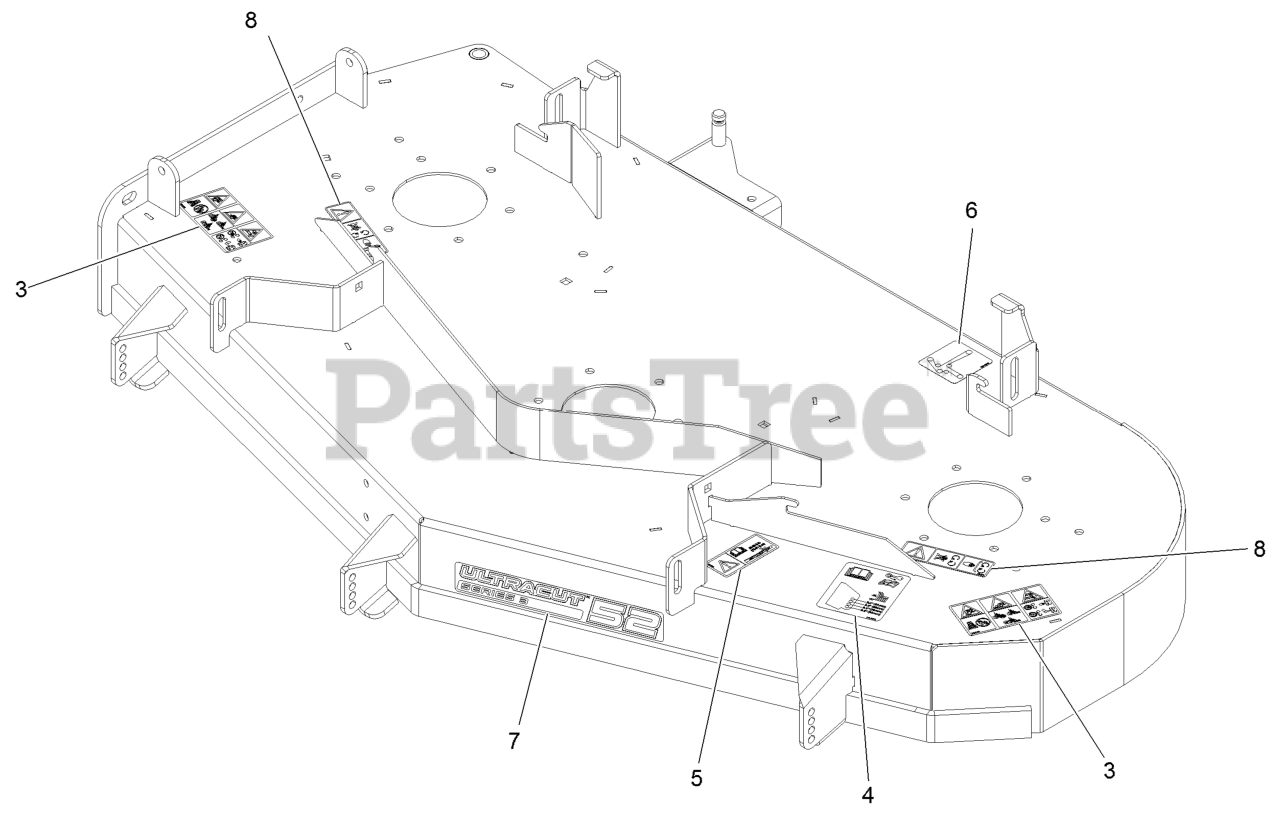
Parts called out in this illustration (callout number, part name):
3	DECAL-DANGER THROWN OBJECTS
4	DECAL-ROLLER, ANTI-SCALP
5	DECAL-BOLT TORQUE
6	DECAL-ROUTING, BELT
7	DECAL-ULTRACUT 52 SERIES
8	DECAL-COVER, MISSING
